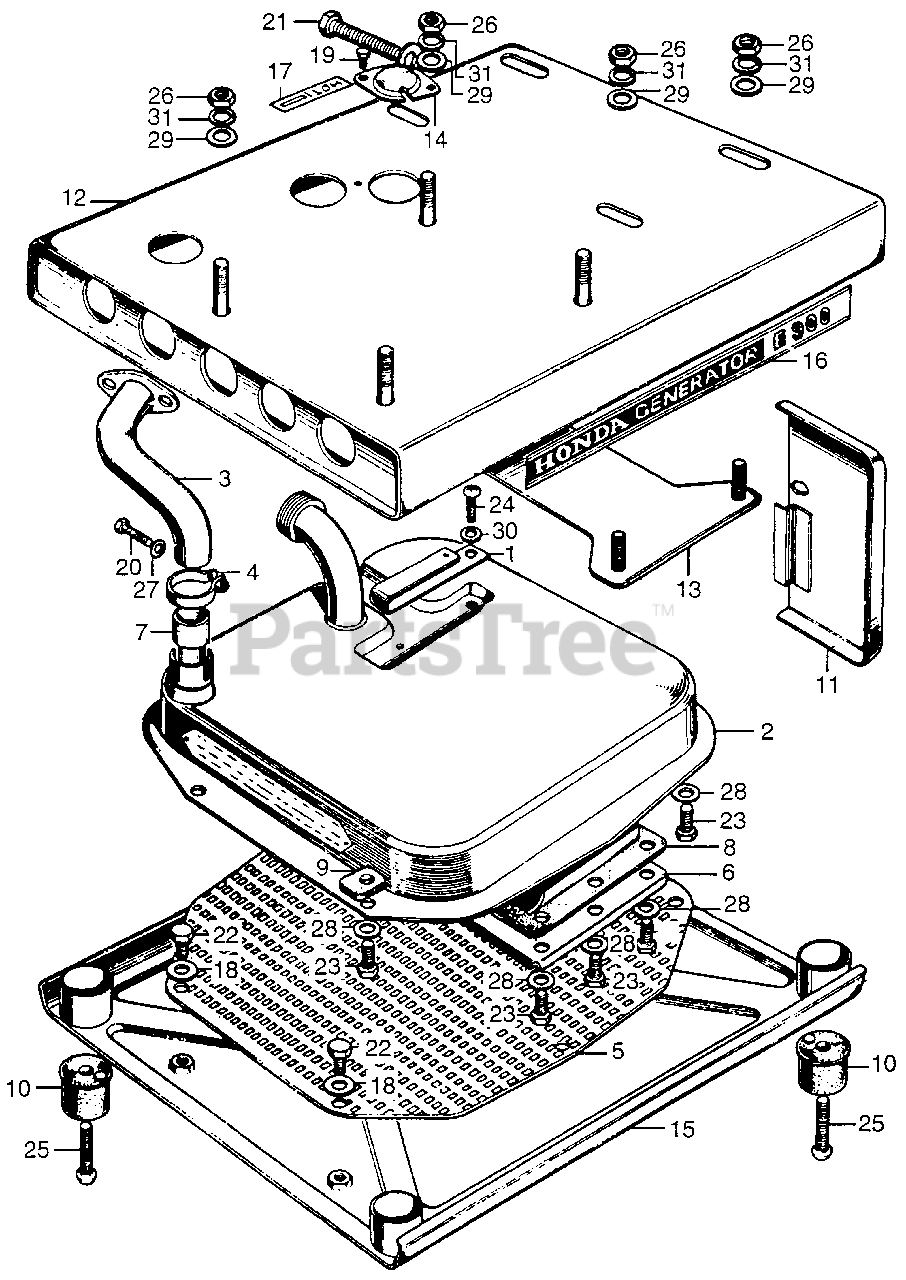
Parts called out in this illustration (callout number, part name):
1	BIMETAL, AUTO CHOKE
2	MUFFLER (NOT AVAILABLE)
3	PIPE, EX. (NOT AVAILABLE)
4	CONNECTOR, EX. PIPE
5	PROTECTOR, MUFFLER
6	COVER, SPARK ARRESTER (LOWER) (NOT AVAILABLE)
7	SEAL, EX. PIPE
8	GASKET, SPARK ARRESTER
9	STOPPER, PROTECTOR
10	RUBBER (LOWER)
11	COVER, R. SIDE *PB6M* (CRYSTAL BLUE METALLIC)
11	COVER, R. SIDE *R8* (BRIGHT RED)
12	BED, ENGINE *Y20* (CLOUD WHITE)
12	BED, ENGINE *NH10M* (DARK SILVER METALLIC)
13	SET BOLT, ALTERNATOR
14	COVER, BIMETAL
15	PLATE (LOWER)
17	PLATE, EX. CAUTION
18	WASHER, SHIFT DRUM SIDE (NOT AVAILABLE)
19	BOLT, HEX. (5X8)
20	BOLT, HEX. (5X28)
21	BOLT, HEX. (8X50)
22	BOLT, HEX. (6X12)
23	BOLT, HEX. (6X16)
24	SCREW, PAN (5X8)
25	SCREW, PAN (6X30)
26	NUT, HEX. (8MM)
27	WASHER, PLAIN (5MM)
28	WASHER, PLAIN (6MM)
29	WASHER, PLAIN (8MM)
30	WASHER, SPRING (6MM)
31	WASHER, SPRING (8MM)
